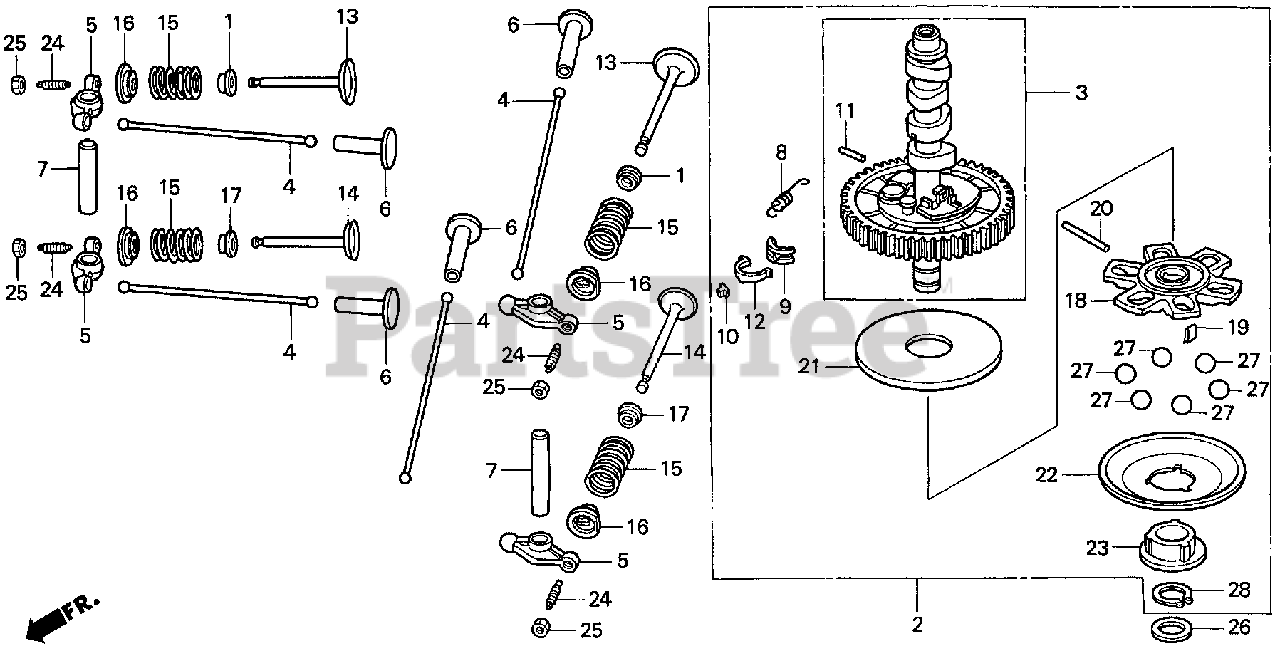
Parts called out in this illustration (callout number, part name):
1	SEAL, VALVE STEM
2	CAMSHAFT ASSY.
3	CAMSHAFT
4	ROD, PUSH
5	ARM, VALVE ROCKER
6	LIFTER, VALVE
7	SHAFT, ROCKER ARM
8	SPRING, WEIGHT RETURN
9	HOLDER, DECOMPRESSION PIN
10	PIN A, DECOMPRESSION
10	PIN B, DECOMPRESSION
10	PIN C, DECOMPRESSION
10	PIN D, DECOMPRESSION
10	PIN E, DECOMPRESSION
11	ROD, DECOMPRESSION
12	SPRING, DECOMPRESSION PIN HOLDER
13	VALVE, IN.
14	VALVE, EX. (STELITE)
15	SPRING, VALVE
16	RETAINER, IN. VALVE SPRING
17	SEAT, VALVE SPRING
18	HOLDER, GOVERNOR WEIGHT
19	PLATE, GOVERNER WEIGHT HOLDER
20	PIN, GOVERNOR WEIGHT HOLDER
21	PLATE, GOVERNOR (LOWER)
22	PLATE, GOVERNOR SLIDER
23	SLIDER, GOVERNOR
24	SCREW, TAPPET ADJ.
25	NUT, TAPPET ADJ.
26	WASHER, THRUST (17.2MM)
27	BALL, STEEL (18)
28	CIRCLIP (OUTER) (17MM)
